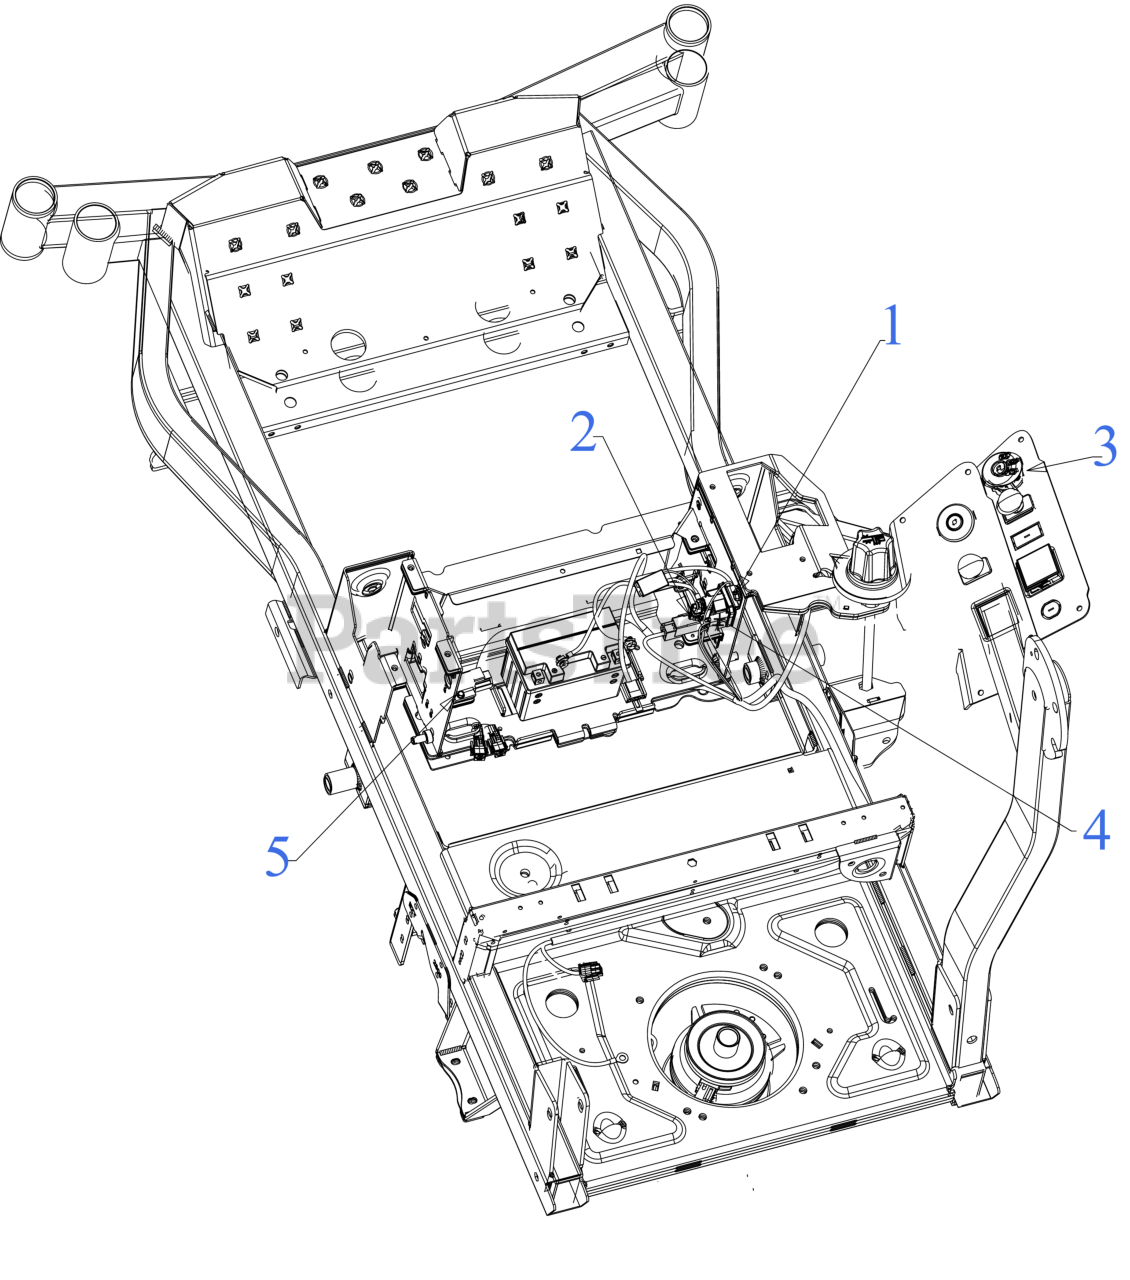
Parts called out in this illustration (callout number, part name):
1	SCREW 1/4-20X.625
2	INTERLOCK SWITCH (NO/NC)
3	KEY SWITCH (3 POS 6 PIN)
4	MAIN HARNESS
5	SHOULDER SCREW
